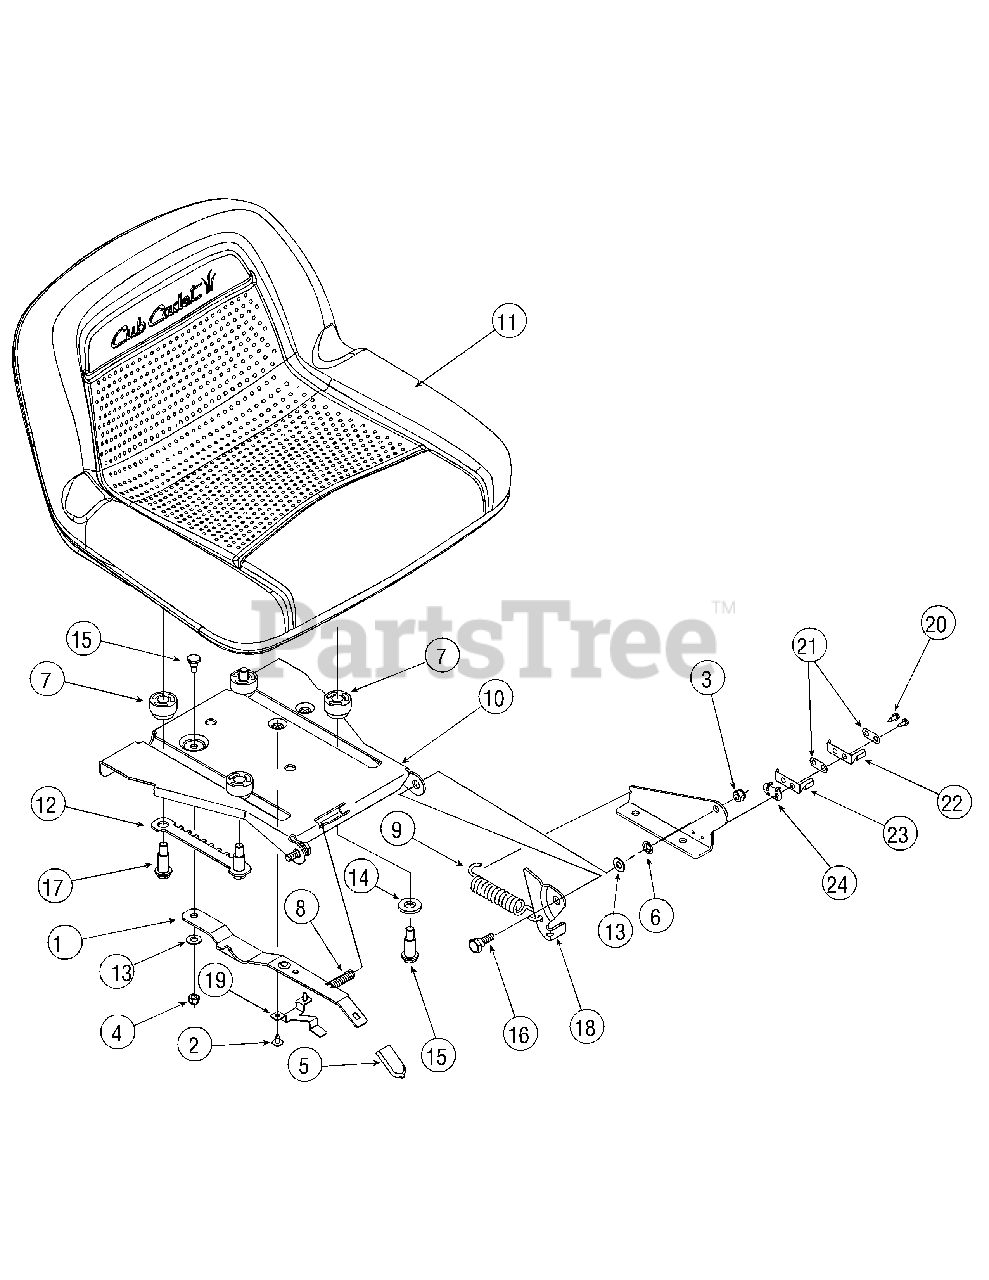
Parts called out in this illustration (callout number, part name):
2	Screw, #10-16, 0.375
3	Nut, Nylon Lock, 5/16-18, Gr5
4	Nut, Nylon Lock, 1/4-20
4	Nut, Nylon Lock, 1/4-20 GrF
5	Grip, Seat, Adjustment (Yellow)
6	Nut, Speed, .3125 ID
7	Spacer, Seat, Adjustment
8	Spring, Compression .41 OD x 1.50
9	Spring, Extension, .80 Dia x 4.6 Lg.
11	Seat, Cub Cadet, Medium Back
12	Selector, Seat, Adjustment
13	Washer, Flat, .344 x .688 x .065
13	Washer, Flat, .344 x .620 x .033
14	Washer, Flat, .531 x 1.062 x .134
15	Screw, Shoulder, .340 x .285, 1/4-20
16	Shoulder, Screw .437 x .286 Lg
17	Screw, Shoulder, .50 x.925, 3/8-16
18	Bracket, Seat Lift
19	Stop, Seat, Adjustment
20	Screw, #8-18 x .50
21	Plate, Insulator
22	Spring Switch, Inner
23	Spring Switch, Outer
24	Plate, Insulator Boss
